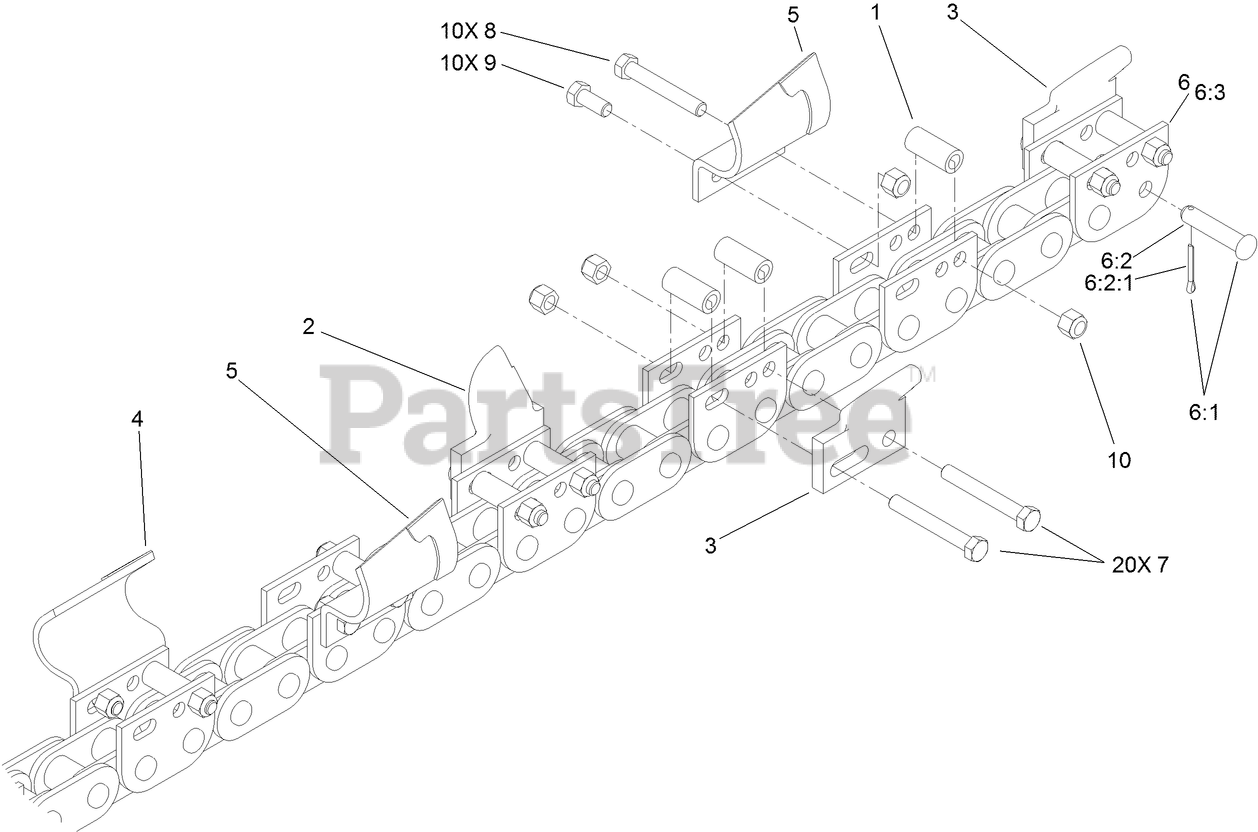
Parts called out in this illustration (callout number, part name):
1	SPACER-TUBE
2	TOOTH- ROCK, LH
3	TOOTH-ROCK, RH
4	TOOTH-SOIL, LH
5	TOOTH-SOIL, RH
6	CHAIN-BARE, 20 STATION
6:1	PIN-CONNECTING
6:2	PIN-CONNECTING (61MM)
6:2:1	PIN-COTTER
6:3	LINK REPAIR KIT
7	SCREW-HH
8	SCREW-HH
10	NUT-HEX
